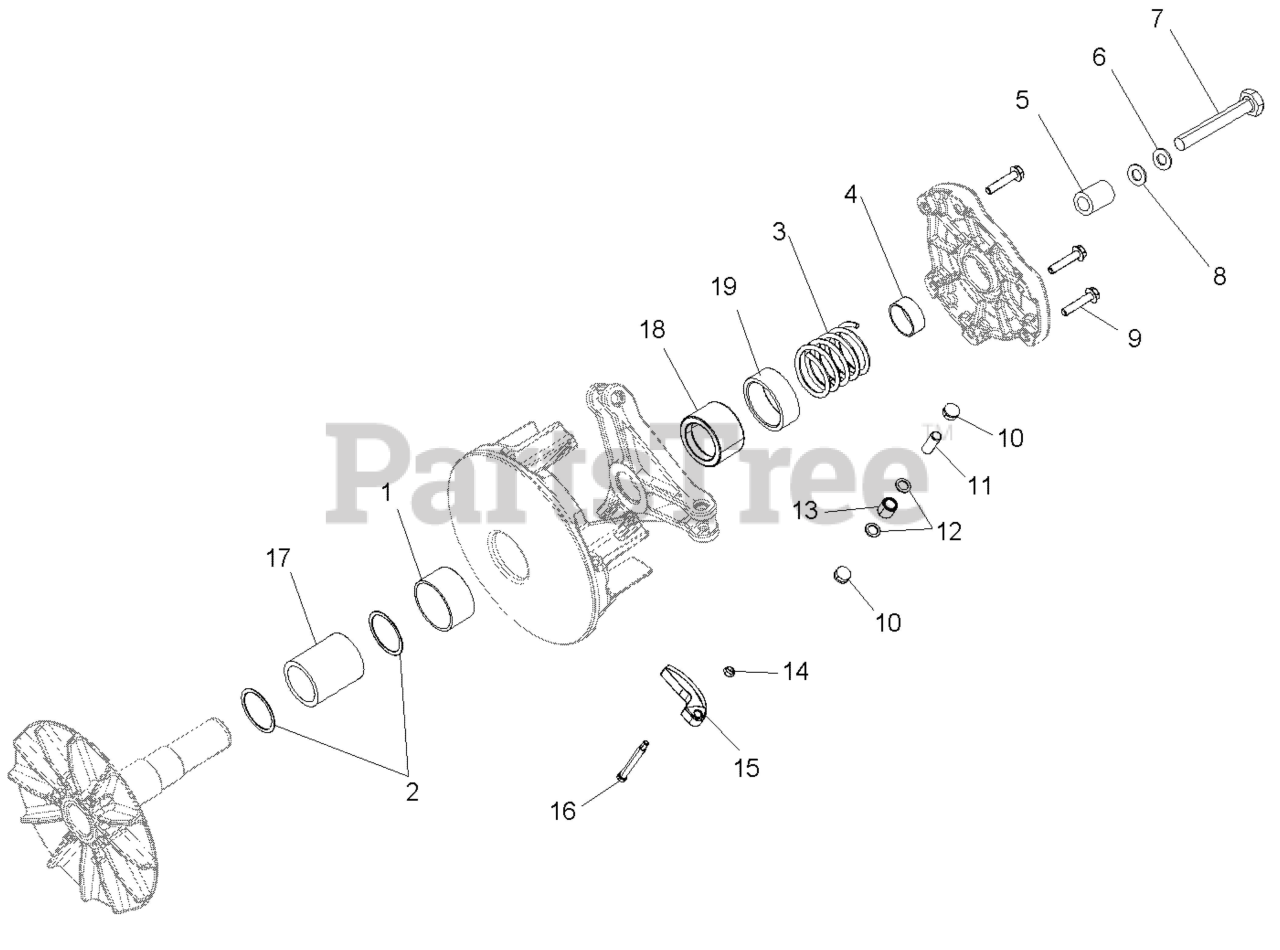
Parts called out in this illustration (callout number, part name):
1	ASM,CLUTCH,DRIVE,BASIC,BEARING
1	BEARING-DU,1.75ID
2	WASHER-CLUTCH,VESPEL
3	SPRING-CLUTCH, 35-240
4	BEARING COVER, .75IN
6	WASHER LOCK
7	BOLT-CLUTCH ATV,7/16X20X8
8	WASHER(10) *
9	SCR-1/4-20X1.25 HX/FL GR5
10	BUTTON,CLUTCH,RUBBER BACKED
11	PIN-ROLLER,(10)
12	WASHER-CLUTCH,SPIDER ROLLER
12	WASHER
13	ROLLER/BUSHING ASM.(3) **
14	NUT FLEXLOC(10)
15	WEIGHT-SHIFT,25-52G,PM
16	BOLT,SHOULDER(10)
17	BEARING-NEEDLE
18	SPACER-CLUTCH
19	SPACER-CLUTCH,LIMITER
